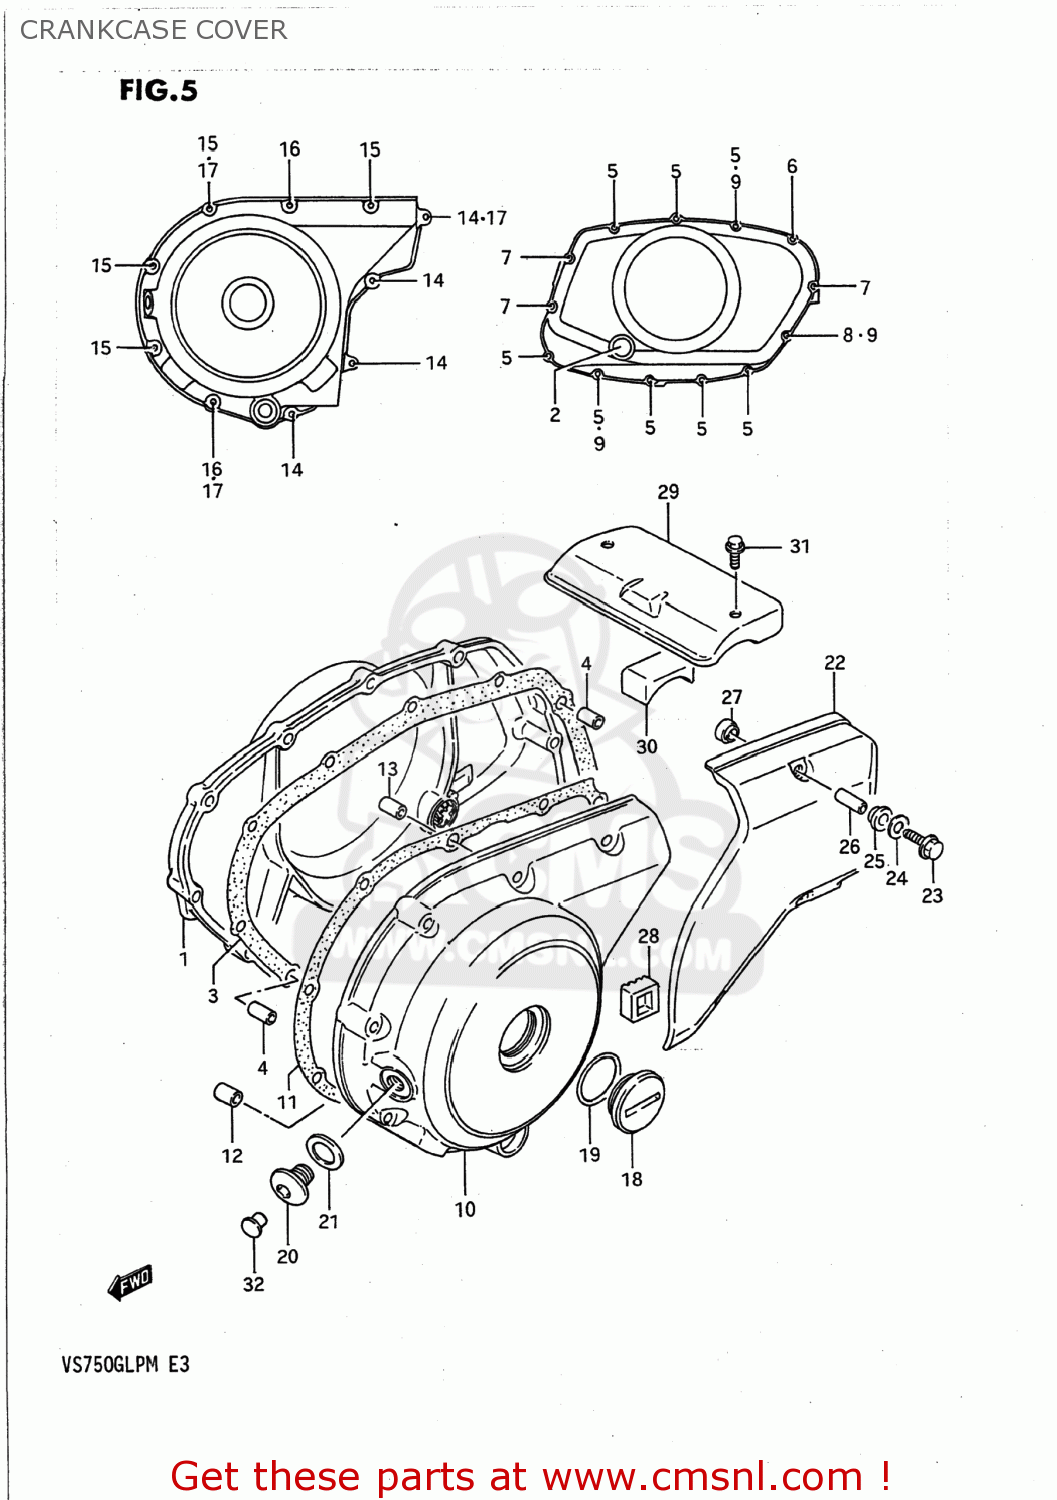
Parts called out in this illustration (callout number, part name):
1	COVER,CLUTCH
2	LENS,OIL LEVEL CHECK
3	GASKET,CLUTCH COVER (NAS)
4	PIN
5	BOLT
6	BOLT
7	BOLT
8	BOLT
9	GASKET(5.8X13X1.2) (NAS)
10	COVER
11	GASKET,MAGNETO COVER (NAS)
12	PIN (11X20)(SUS)
13	PIN
14	BOLT
15	BOLT
16	BOLT
17	GASKET(5.8X13X1.2) (NAS)
18	Chrome Crankshaft Plug
19	O RING(D:3.1,ID:32.7)
20	PLUG,14X12
21	GASKET(14X19.2X2) (NAS)
22	COVER,SECONDARY GEAR CASE
23	BOLT
24	WASHER
25	WASHER(8.7X15X2.1)
26	SPACER
27	WASHER(8.7X16X5)
28	DAMPER,SECONDARY COVER
29	COVER,STARTER MOTOR
30	DAMPER,MOTOR COVER
31	BOLT
32	CAP(OD:12)
